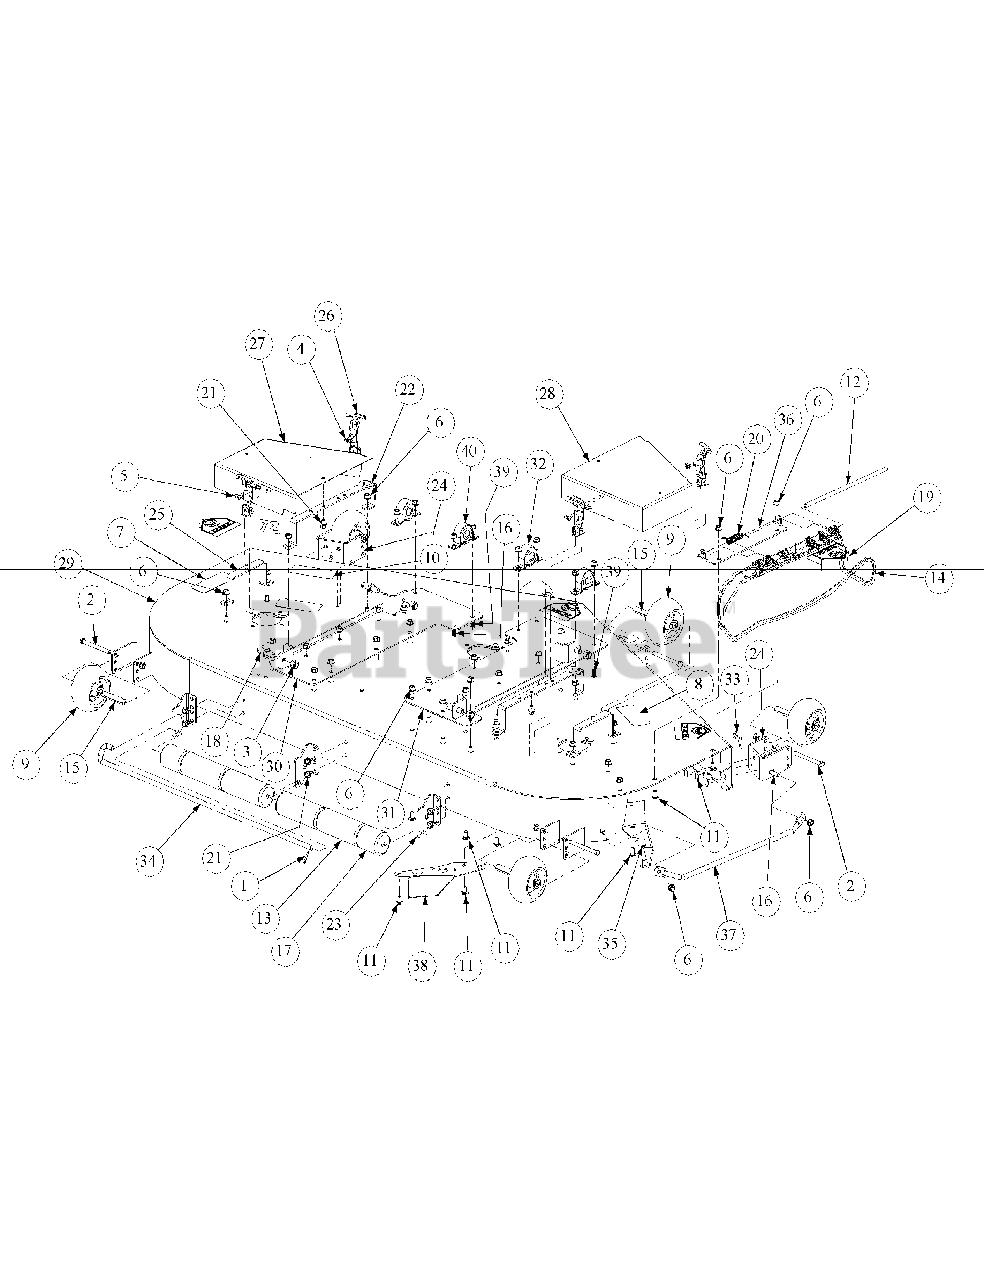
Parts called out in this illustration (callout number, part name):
1	Cotter Pin, .125 Dia. x 1.0
2	Hex Cap Screw, 3/8-16, 3.75
3	Lock Nut, Nylon Insert, 1/2-13
4	Lock Nut, Nylon Insert, #10-32
5	Phillips Head Screw, #10-32 x 1/2
6	Flange Lock Hex Nut, 3/8-16
7	Decal, Rotating Blade
8	Decal, Warning Shield Missing
9	Complete Wheel, 5.00 Dia.
10	Command Cut Large
11	Carriage Bolt, 3/8-16 x .75 Lg.
12	Pin, .375 x 14.06
13	Front Roller
14	Chute Deflector
15	Wheel Spacer
16	Carriage Bolt, 3/8-16 x 1
17	Grass Catcher Roller
18	Pin, 5/8 Dia. x 1.2 Lg.
19	Decal, Danger Hand and Feet
20	Torsion Spring, 0.4ID x 2.16Lg
21	Hex Index Washer Screw, 3/8-16, .5
22	Belt Cover Support
23	Deck Roller Mount Bracket
24	Anti-Scalp Wheel Front Mount Bracket
25	Outer Belt Cover Support Assembly
26	T-Handle Latch Draw
27	Left Hand Deck Belt Cover Weldment
28	Right Hand Deck Belt Cover Weldment
29	72 Deck Assembly
30	Left Hand Deck Weldment Bracket
31	Right Hand Deck Weldment Bracket
32	Pillow Block, Steel
33	Decal, 72"
34	Roller Pin
35	Chute Bracket
36	Chute Bracket
37	Finger Guard
38	Discharge Baffle Weldment
39	Carriage Screw, 3/8-16 x 1.25
40	Pillow Block, Bronze
